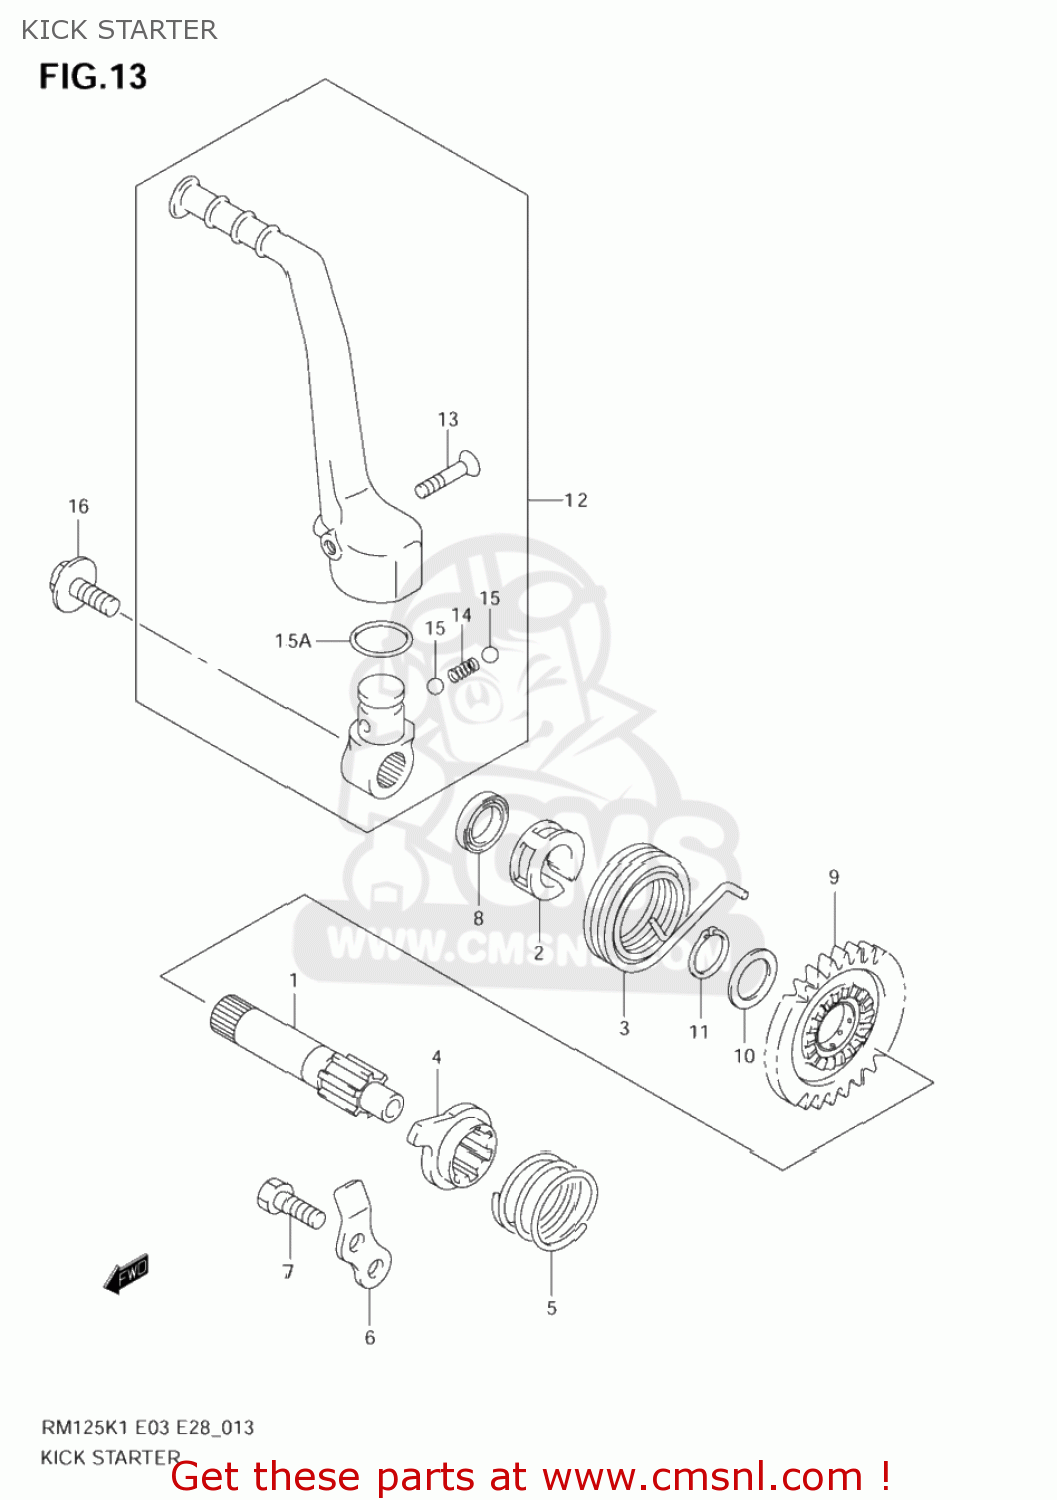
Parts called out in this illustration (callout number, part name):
1	SHAFT,KICK STARTER
2	GUIDE,KICK STARTER SFT SPRING
3	SPRING
4	STARTER,KICK
5	SPRING
6	GUIDE,KICK STARTER
7	BOLT
8	SEAL,OIL(15.8X24X5)
9	GEAR,KICK STARTER DRIIVE
10	SHIM(16X24X0.5)
11	CIRCLIP 16MM
12	LEVER ASSY,KIC
13	SCREW(6X27.5)
14	SPRING
15	BALL
15A	O RING,KICK STARTER
16	BOLT(8X14)
